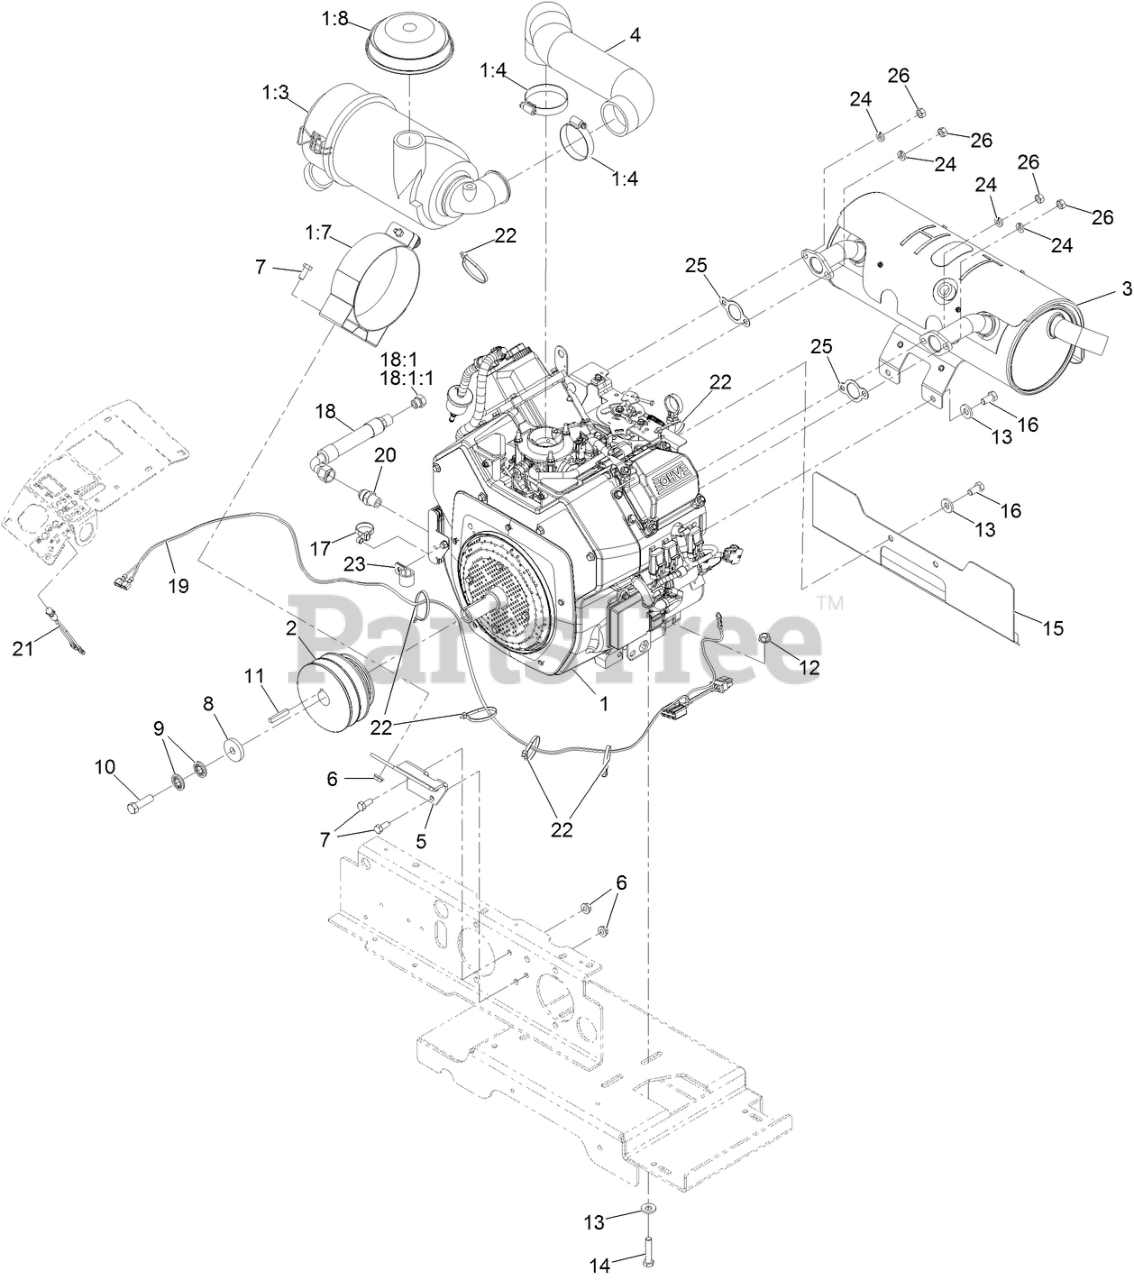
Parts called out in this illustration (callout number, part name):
1:3	AIR CLEANER CANISTER ASM
1:4	CLAMP-HOSE
1:7	BRACKET-FILTER, AIR
1:8	HOOD-CLEANER, 2" AIR INTA
3	Muffler-EFI Navigator-8000
4	HOSE-EFI AIR INTAKE
5	BRACKET-FILTER, AIR
7	SCREW-HH
8	WASHER-CLUTCH
9	WASHER-SPRING
10	SCREW-HH
11	KEY-SQUARE
12	NUT-HHF, WHIZ
13	WASHER-BELLEVILLE
14	SCREW-HH
15	SHIELD-EXHAUST
16	SCREW-HH
17	Tie, Cable
18	OIL DRAIN HOSE ASM
18:1	PLUG-HH
18:1:1	O-RING
19	HARNESS-LIGHT INDICATOR (
20	FITTING-STRAIGHT
21	INDICATOR-LED, RED
22	TIE-CABLE
23	CLIP-LOOM
24	WASHER-LOCK
25	GASKET (KOHLER)
26	NUT-HEX
